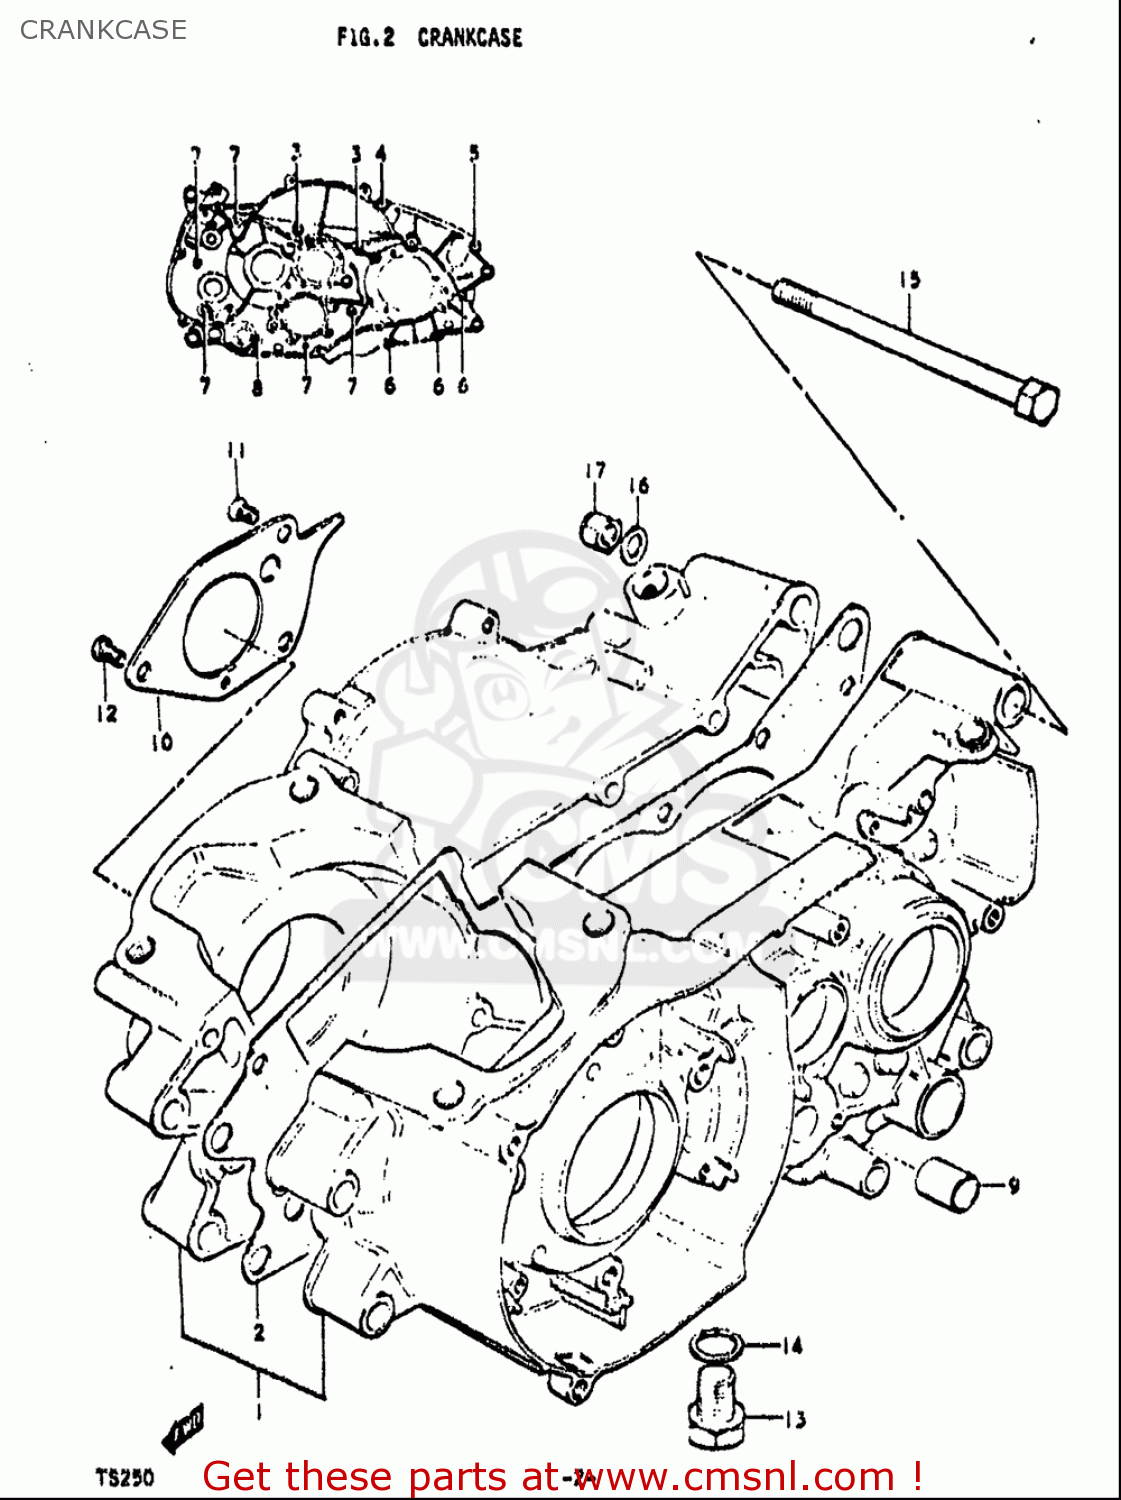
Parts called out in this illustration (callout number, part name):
2	GASKET,CRANKCASE (NAS)
3	SCREW
4	SCREW
5	SCREW
6	SCREW
7	SCREW
8	SCREW
9	PIN
10	PLATE,OIL RESERVOIR
11	SCREW
12	SCREW
13	PLUG
14	GASKET(14X19.2X2) (NAS)
15	BOLT(10X120)
16	WASHER
